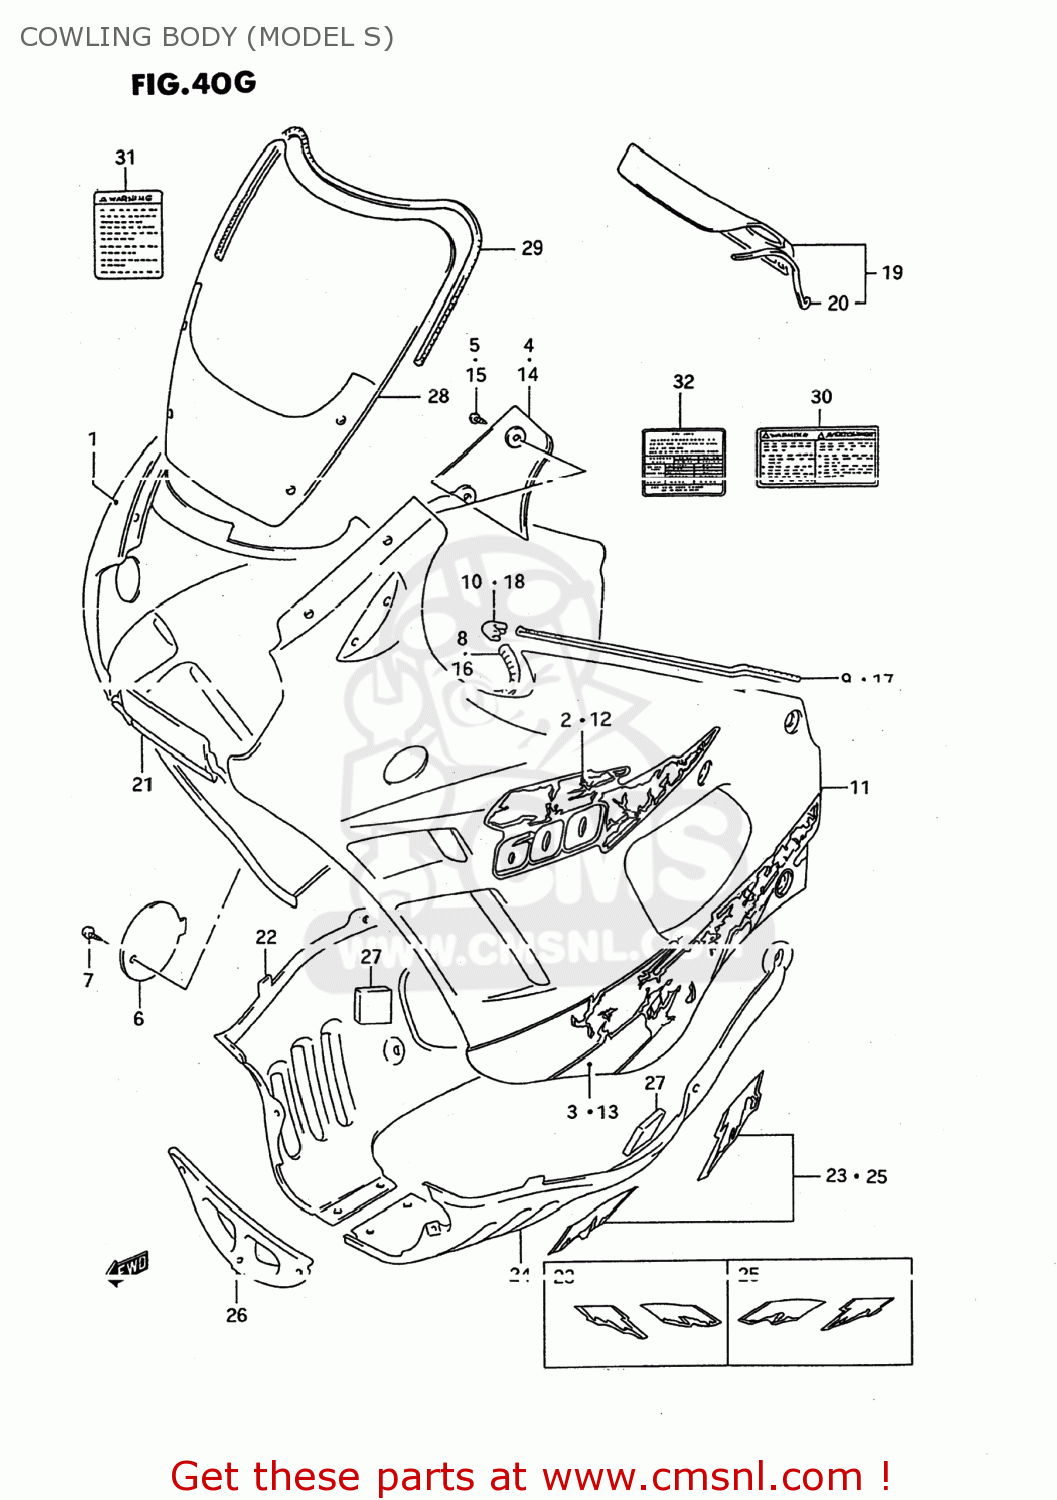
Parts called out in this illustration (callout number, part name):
1	COVER ASSEMBLY,COWLING,RIGHT
2	TAPE,BODY COWLING SIDE,UPPER
3	TAPE,BODY COWLING SIDE,RIGHT
4	COVER,METER SIDE,RIGHT
5	SCREW
6	LID,OIL
7	SCREW(6X16)
8	MOLD,COWLING
9	MOLDING
10	JOINT,MOLDING END
11	COVER ASSEMBLY,COWLING,LEFT
12	TAPE,BODY COWLING SIDE,UPPER
13	TAPE,BODY COWL SIDE,L
14	COVER,METER SIDE,L(GREEN)
15	SCREW
16	MOLD,COWLING
17	MOLDING
18	JOINT,MOLDING END
19	COVER,METER
20	MOLDING
21	PANEL,COWLING CTR
22	COVER,COWLING UNDER,R
23	TAPE SET,COWL UNDER,R
24	COVER,COWLING UNDER,L
25	TAPE SET,COWL UNDER,L
26	COVER,COWLING UNDER FR
27	CUSHION,UNDER COWLING
28	WINDOW,COWLING
29	MOLDING,WINDSCREEN
30	LABEL,GENERAL WARNING
31	LABEL (WARNING SCREEN)
32	LABEL (TIRE INFORMATION)
